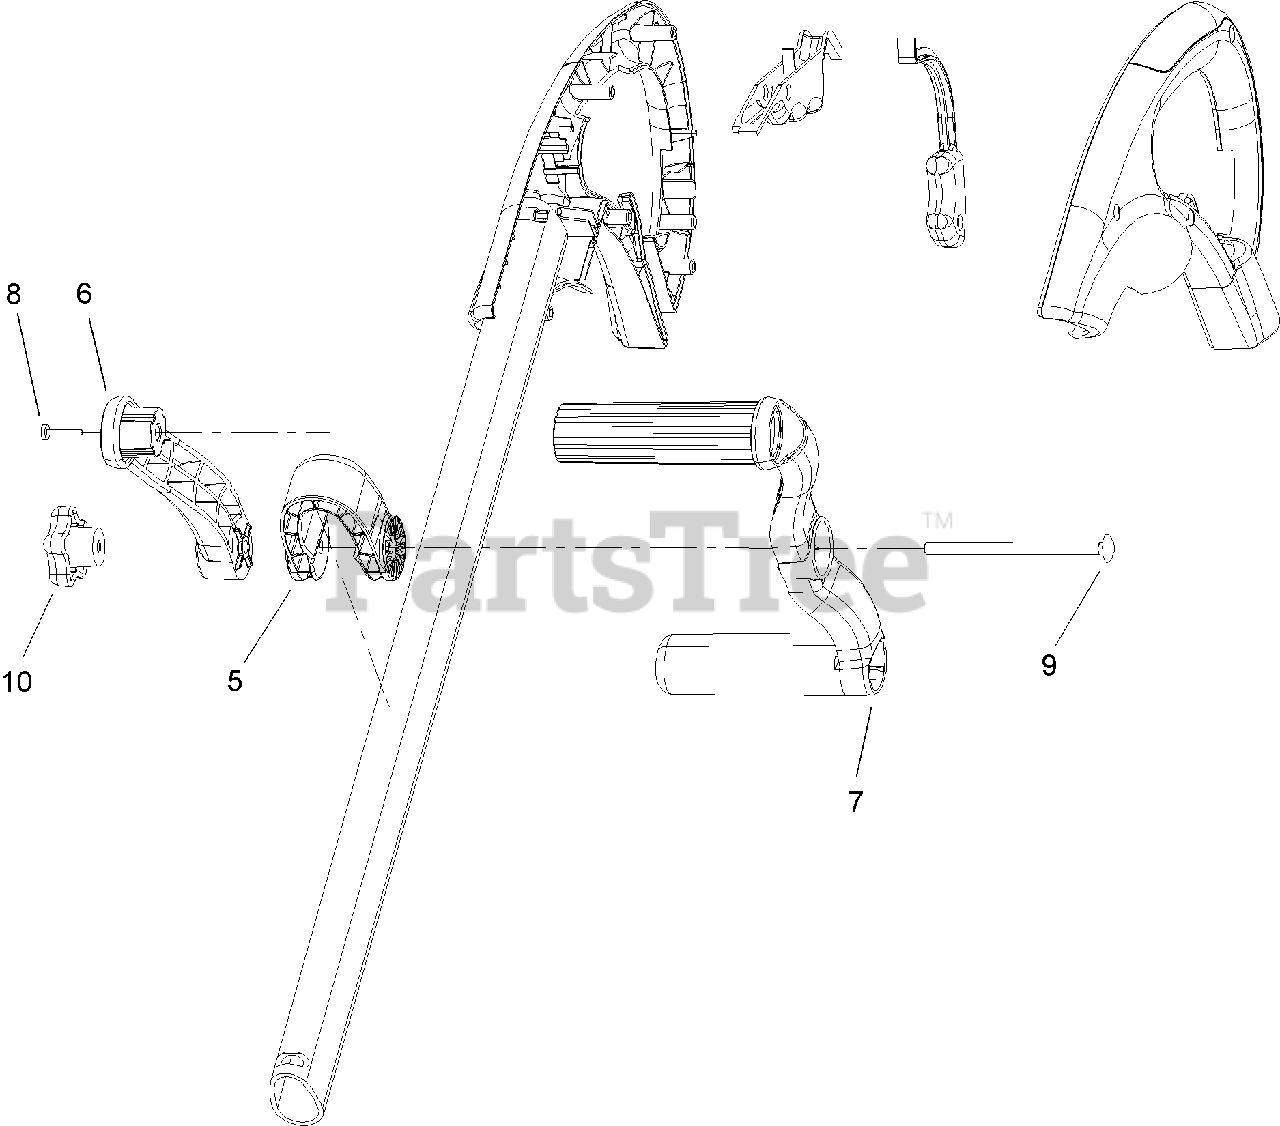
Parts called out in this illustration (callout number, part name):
5	COLLAR-HANDLE, ASSIST
6	HANDLE-ASSIST, RIGHT
7	HANDLE-ASSIST, LEFT
7	ASSIST HANDLE ASM
8	SCREW-PPH
9	SCREW-CARRIAGE
10	KNOB-HANDLE
